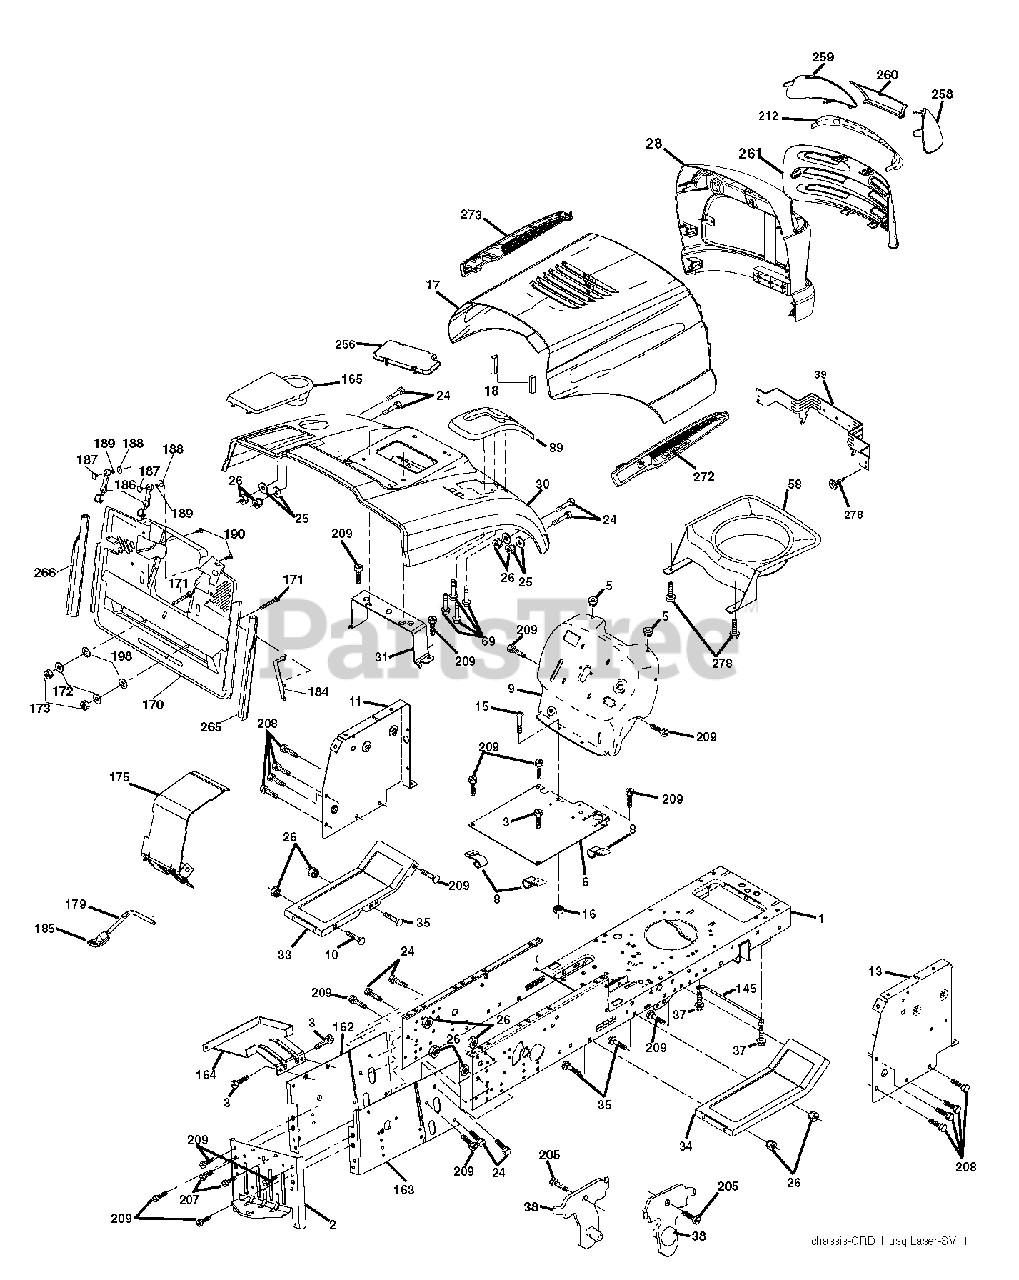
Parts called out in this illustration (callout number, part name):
2	DRAWBAR
3	SCREW 3/8-16X3/4
5	BUMPER.RUBBER.HOOD
6	PLATE
8	CLIP,INSULATOR
9	DASH.SLK.LT.PL.CC.NA.NHM.CE
10	BOLT D
11	PANEL.DASH.LH.LTX
13	PANEL ASM, DASH RH
16	NUT
17	HOOD.PNT.LASER.SV.LT.668
18	BUMPER.HOOD.LARGE.1.75"
25	WASHER
26	NUT
28	GRILLE.HUSQ.LASER.LT.668
30	FENDER.PNT.CRD.MS-668
31	BRACKET SUPPORT FENDER
33	FOOTREST.LH.BLACK
34	FOOTREST.RH.BLACK
37	SCREW LT
38	BRACKET ASM PIVOT MOWER REAR
39	BRACKET PIVOT
69	SCREW.HI-LO.CONSOLE
89	CONSOLE.CRD.AUTO.BLACK (2 2)
145	ROD.PIVOT.HOOD
162	BRACKET
163	BRACKET EXTEN CHASSIS RH CRD
165	COVER.BATTERY.CRD.BLACK
172	WASHER
175	DOOR TRAP
179	ROD PIVOT FBI
184	BRACKET.ACTUATOR.BAGGER.SRD
186	LATCH ASSY
187	WELDNUT
189	LOCKWASHER (3 2)
190	SCREW
207	SCREW, 5/16-18 X 1/2
208	SCREW 3/8-16X1/2
209	SCREW, 3/8-16X3/4
212	INSERT.LENS.REFLECTIVE
256	FENDER.PNT.CRD
258	LENS LH
259	LENS LH
260	COVER.LENS.HUSQ.LASER.LT.498
261	INSERT.GRILLE.HUSQLASER.LT.498
265	SEALING
266	SEALING
272	VENT.HOOD.LASER.III.SD.RH
278	SCREW.#10 X 0.750.BOS
